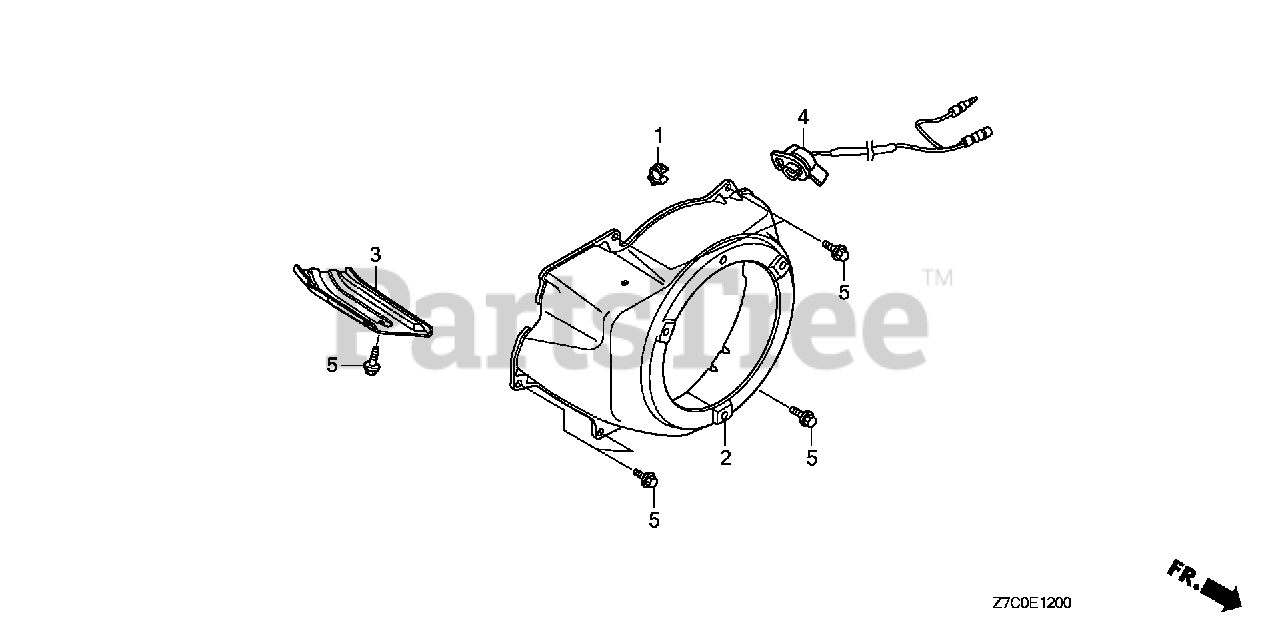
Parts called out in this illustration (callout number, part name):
1	CLIP, TUBE
2	COVER, FAN *R280* (POWER RED)
2	COVER, FAN *NH1* (BLACK)
2	COVER, FAN *NH246* (LOOSY GRAY)
4	SWITCH ASSY., ENGINE STOP
5	BOLT, FLANGE (6X12) (CT200)
